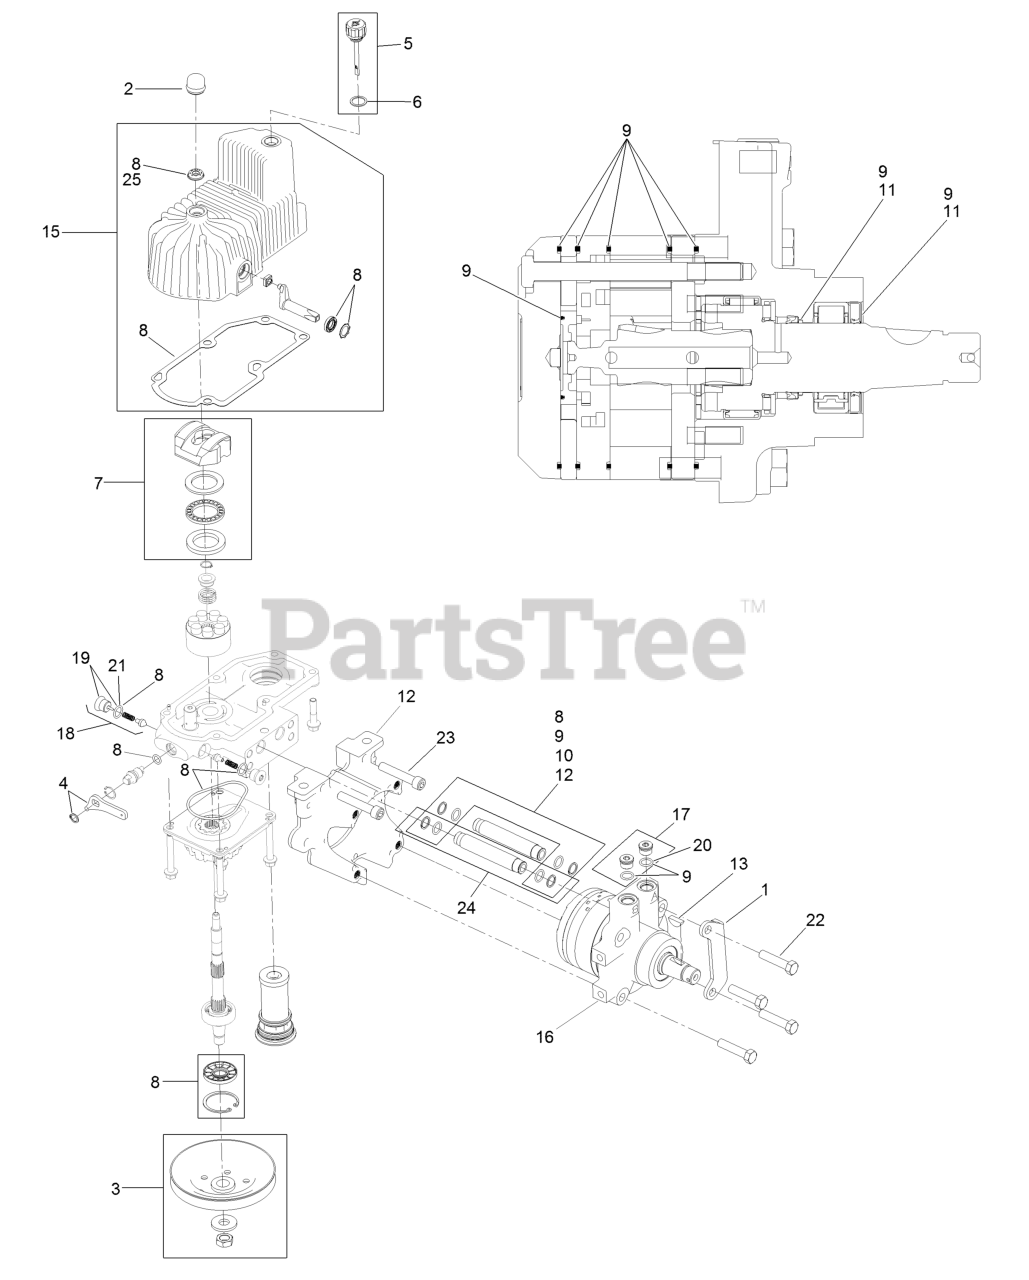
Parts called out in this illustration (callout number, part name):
1	Mount-Shoe, Horse
2	Cover-Shaft, Hydro
3	Pulley Kit
4	Handle-Bypass Valve,Hydro
5	Dipstick-Hydro W/Gasket
6	Gasket-Dipstick, Hydro
7	Swash Block Kit
8	Pump Seal Kit
9	Motor Seal Kit
10	Tube Seal Kit
11	Output Shaft Seal Kit
12	Nose Cup-Uht
13	Key-Woodruff
15	Housing-RH
16	Motor-Hydraulic RH 240Cc
17	Magnetic Plugs Service Kit
18	Check Valve ASM
19	Plug-Check (W/O-Ring)
21	O-Ring-Check Valve
22	Screw HH
23	Screw-HSH
24	Hydraulic Tube Kit
25	Seal-Fan Drive
99	Puller-Pulley
99	Flow Test Kit
